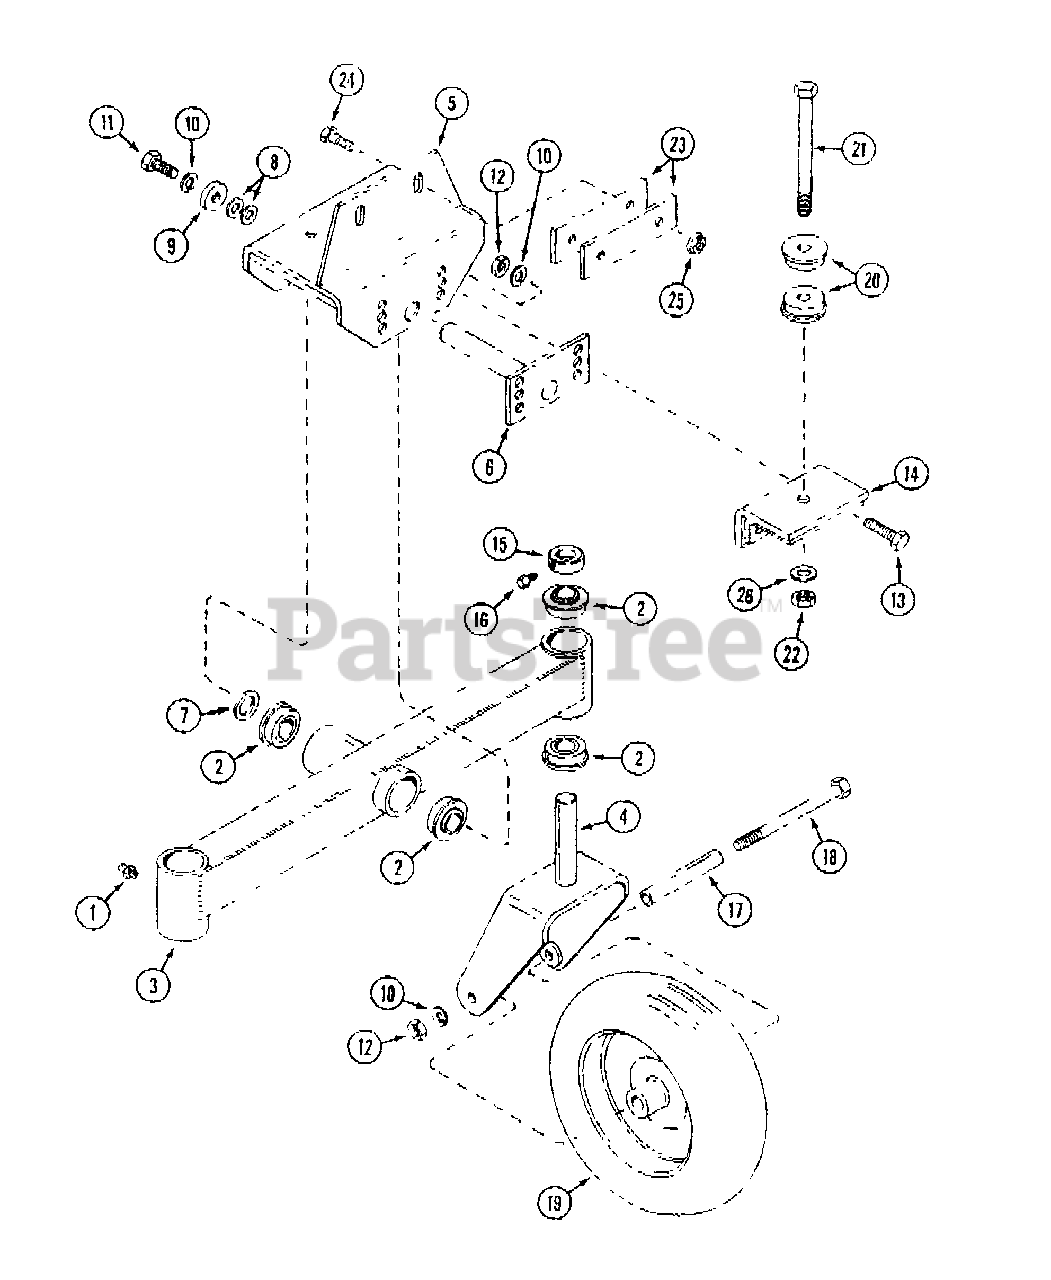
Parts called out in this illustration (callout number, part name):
1	FITTING - lubrication 1/4" - 28
2	BEARING - Ball 1"
3	AXLE - dual wheel
4	FORK - wheel
6	ROD - axle pivot
7	WASHER - 1" x 1-3/4"
8	WASHER - 1/2" x 1"
9	WASHER - 1/2" x 1-3/6"
10	LOCKWASHER - 1/2"
11	BOLT - 1/2" - 13 x 1-1/4"
12	NUT - 1/2" - 13
13	BOLT - 1/2" - 13 x 1-3/4"
14	MOUNT - axle, front extension
15	COLLAR - set 1"
16	SCREW - set 5/16" - 18 x 1/2" square head
18	BOLT - 1/2" - 13 x 7"
19	WHEEL ASSEMBLY
20	BUSHING - tail wheel hub
21	BOLT - 5/8" - 11 x 7-1/2"
22	NOT - 5/8" - 11
23	PLATE - stiffener
24	BOLT - 3/8" - 16 x 1-1/4"
25	NUT - 3/8" - 16 flange lock
26	WASHER - 5/8" x 1-1/2"
